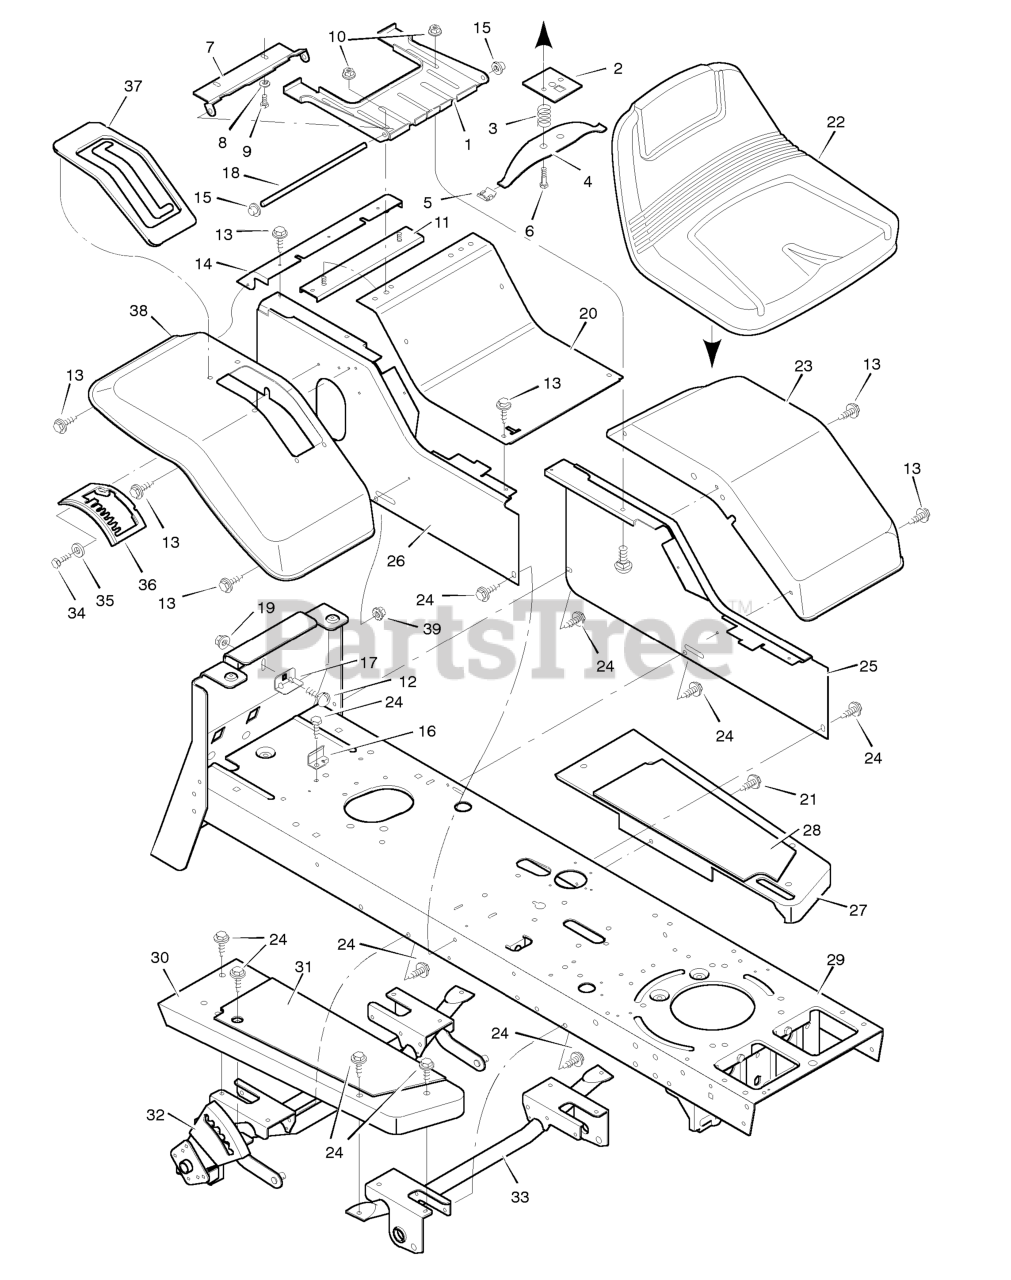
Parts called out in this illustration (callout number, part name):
1	Bracket, Seat
2	Plate Assembly, Switch
3	Spring, Compression
4	Spring, Seat
5	Glide, Spring
6	Bolt, Shoulder
7	Support, Seat
8	Lockwasher
9	Bolt, Hex
10	Locknut, Flange
11	Channel Assembly
12	Bolt, Carriage
14	Insert, Rear
15	Push On Cap
16	Clip, Battery
17	Clamp, Battery
18	Rod, Pivot
19	Locknut
20	Panel, Top
21	Fastener, Panel
25	Panel, Left
26	Panel, Right
27	Running Board, Left
28	Mat, Left
29	Frame Channel
30	Running Board, Right
31	Mat, Right
32	Lifter and Support Assembly
33	Support Assembly, Front
36	Gate, Shift
37	Cover, Shift
38	Fender, Right
39	Locknut
